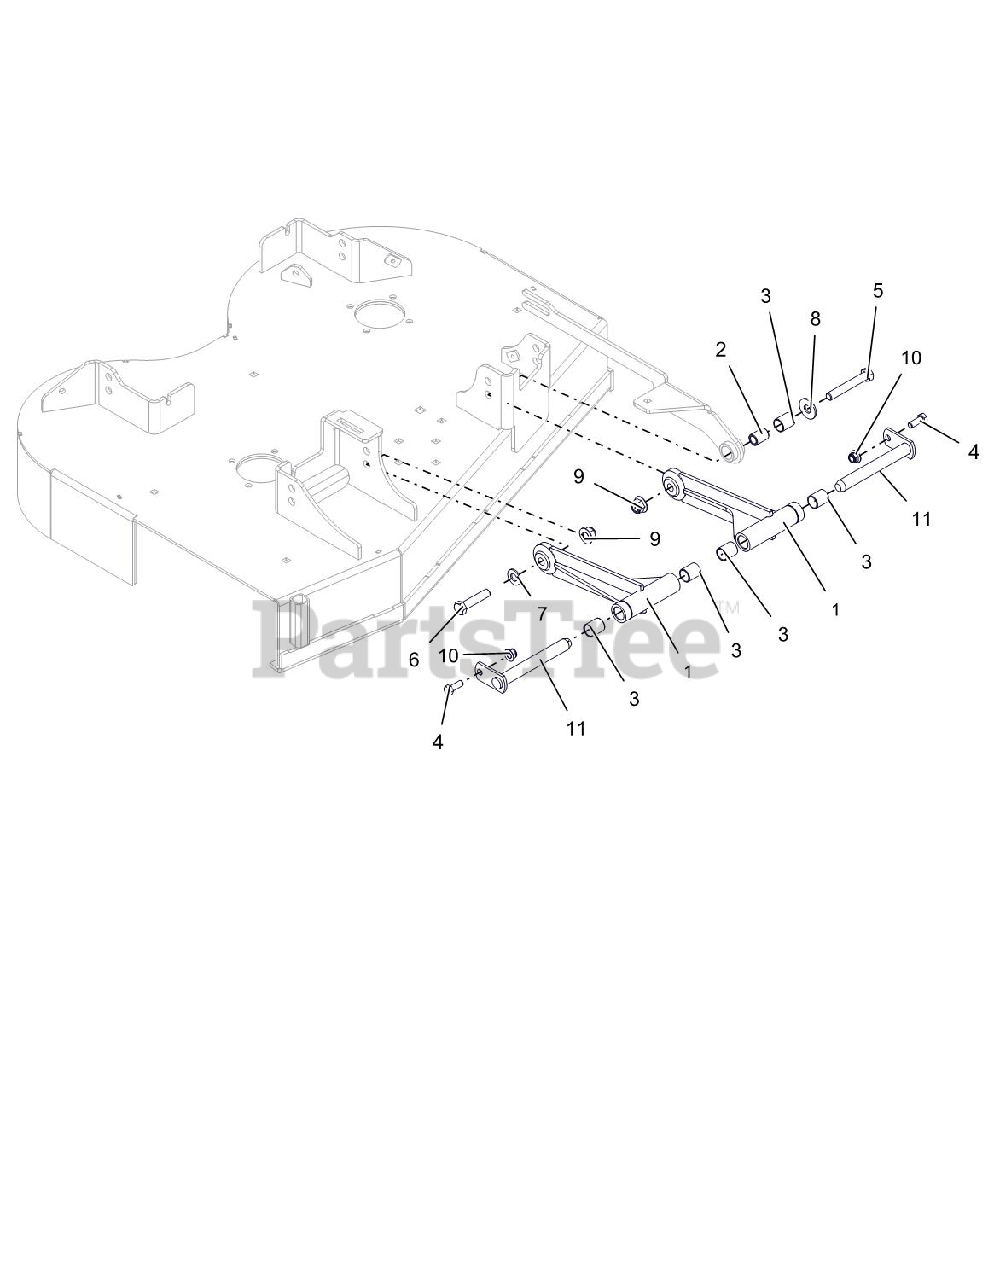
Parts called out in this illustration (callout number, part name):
1	WMT, DRAG LINK
2	BSHG, .515ID X .75ODX 1.080
3	BRG, .750 X .875 X 1.000
4	@BLT-HEX .38-16X1.00 GR5 YWZC
5	@BLT-HEX .50-13X3.25 GR5 YWZC
6	@BLT-HEX .50-13X2.25 GR5 YWZC
7	@WSHR-FL-STL.531X1.06X.095YWZC
8	@WSHR-FL-STL.563X1.38X.109YWZC
9	@NUT-LK-NYL-FLG .50-13 YWZC
10	@NUT-LK-NYL-FLG .38-16 YWZC
11	WELDMENT, MOWER MTG. PIN
